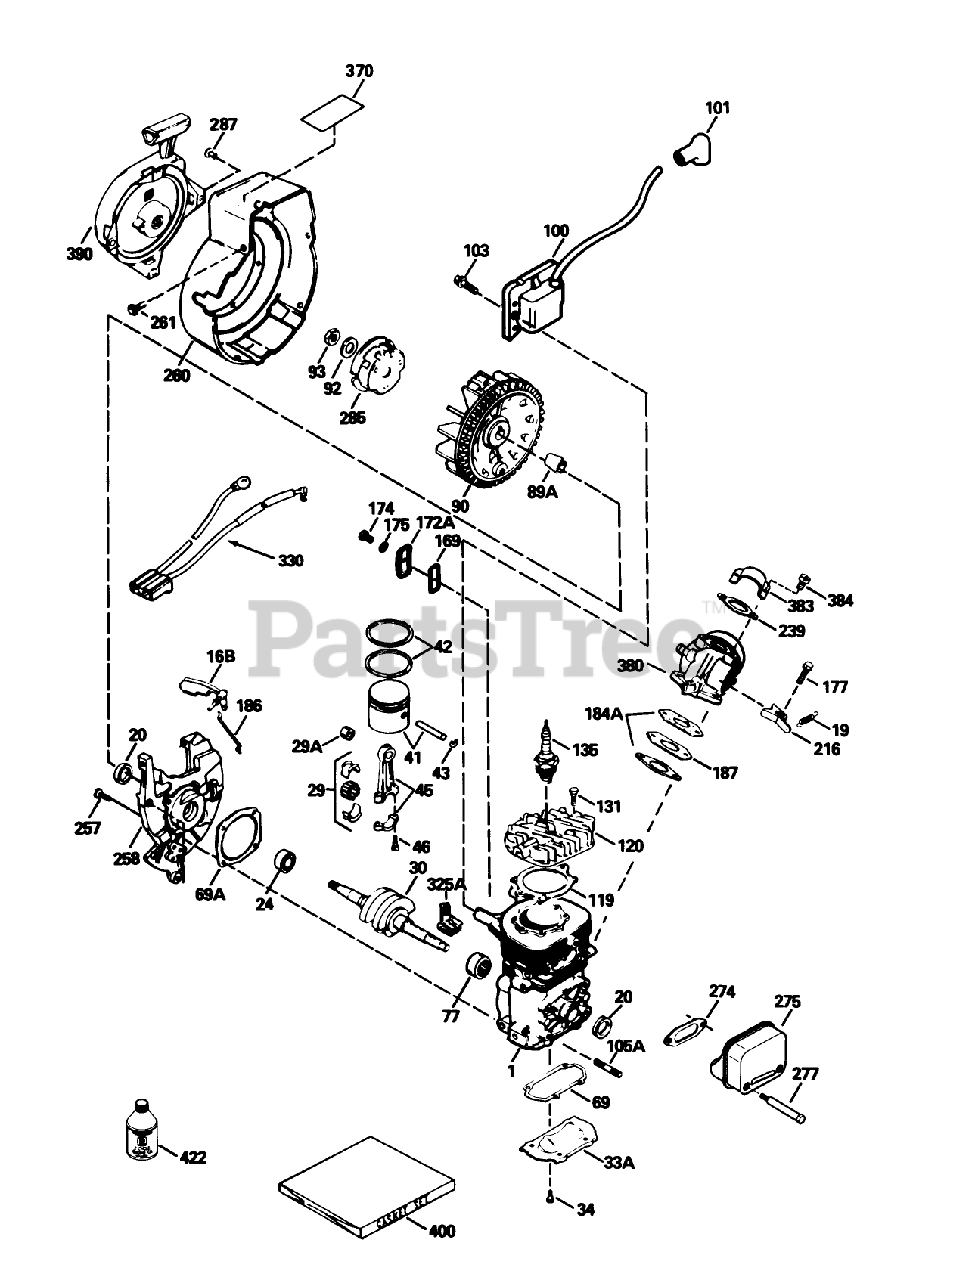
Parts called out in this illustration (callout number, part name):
1	Block Ass-y-Cylinder (Order short block if replacement is required)
16B	Vane-Air
19	Spring-Extention
20	Seal-Oil
24	Bearing-Ball
29	Needle Bearing and Liner Set (37 Needles)
29A	Bearing-Cartridge
30	Crankshaft
33A	Plate-Cover
34	Screw (T-25, 10-24 x 1/2)
41	Piston (Incl. Ref. #43)
42	Ring Set
43	Ring-Retaning
45	Rod Assy.-Connecting (Incl. Ref. #3, 3A 3B)
46	Bolt-Rod, Connecting
69	Gasket-Plate, Cover
69A	Gasket-Cover, Cylinder
77	Bearing-Cartridge
89A	Blade (20 inch)
90	CARB BODY S
92	Washer-Belleville
93	Nut-Flywheel
100	Solid State
101	Cover-Spark Plug
103	Screw
119	Gasket-Head, Cylinder
120	Head-Cylinder
131	Screw (T-30, 1/4-20 x 3/4)
135	Spark Plug-Resistor (R C J 8Y)
169	Cover-Compression, Release
172A	Comp. Release Cover
174	Screw (T-25, 10-24 x 1/2)
175	Washer
177	Screw (5/32 Allen, 1/4-20 x 1)
184A	Gasket-Carburetor
186	Link-Governor
187	Spacer
216	Lever-Adjusting, Rpm
239	2060A77 WIZARD ROTA
257	Screw (T-30, 1/4-20 x 5/8)
258	Base Ass-y-Blower Housing (Incl Ref. #20)
260	Housing-Blower
261	Screw (1/4-20 x 1/2)
274	Gasket-Exhaust
275	Muffler (Incl. Ref. #274 277)
277	Screw (1/4-20 x 2-3/4)
285	Cup-Starter
287	Rivet-Pop
325	Clip-Wire
330	Harness-Wire
380	Carburetor (Incl. Ref. #184A)
383	Baffle-Carburetor
384	Screw
390	Starter-Rewind
400	Gasket Set
422	2-Cycle Oil (8oz)
